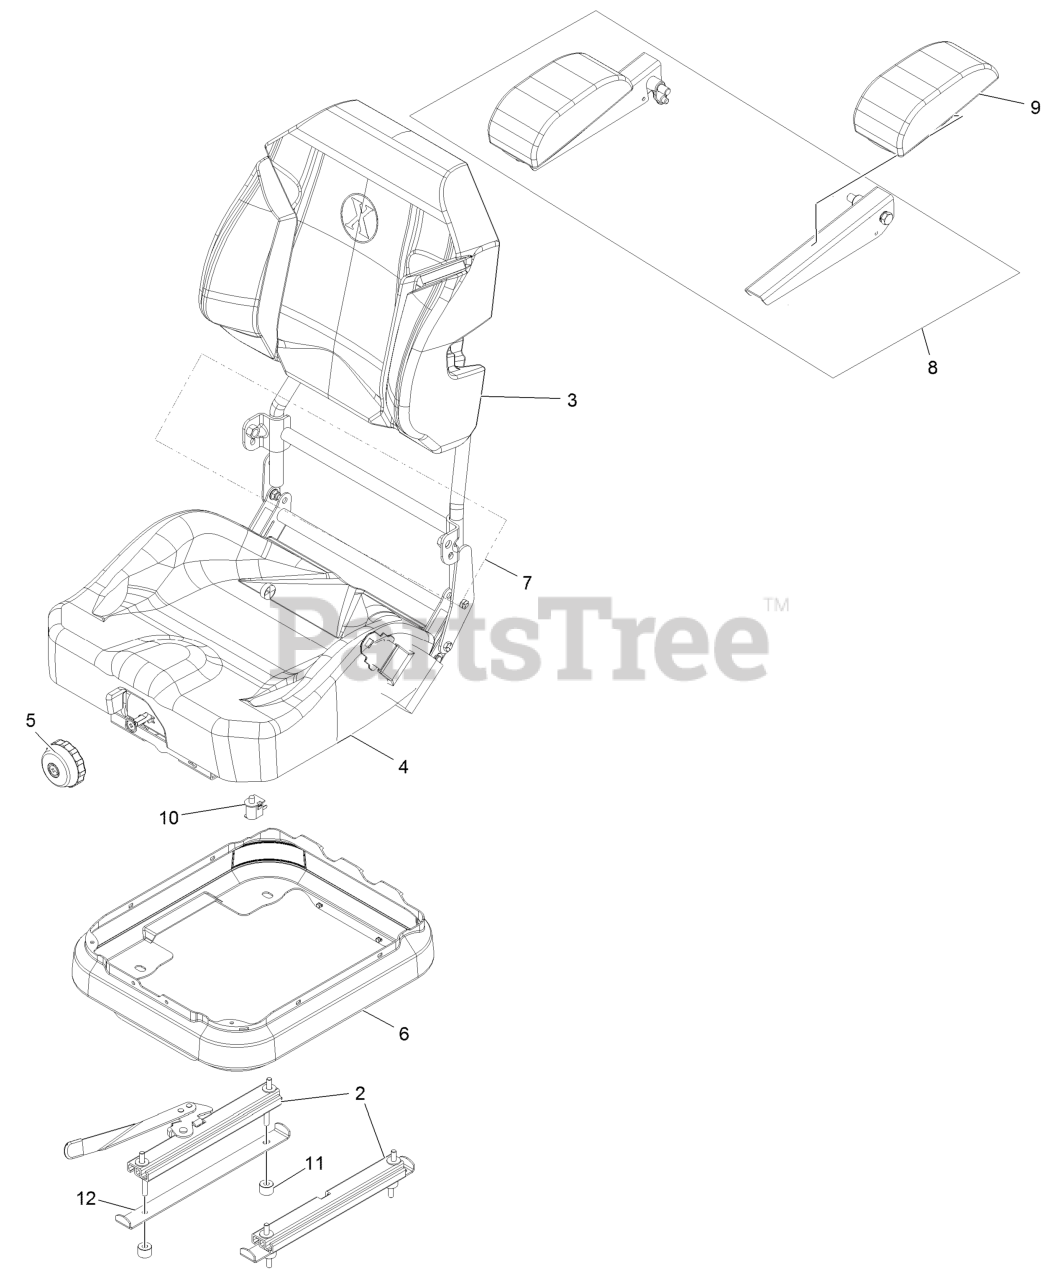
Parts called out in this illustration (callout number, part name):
2	SEAT TRACK SET
3	COVER-BACK 311463VN500
4	COVER-CUSHION 311464VN500
5	KNOB-ADJUSTER
6	COVER-SUSPENSION, BELLOWS
7	SEAT BELT SERVICE KIT
8	KIT-ARM REST SET
9	KIT-ARM REST PADS
10	SWITCH-BAIL
12	STOP, SEAT
